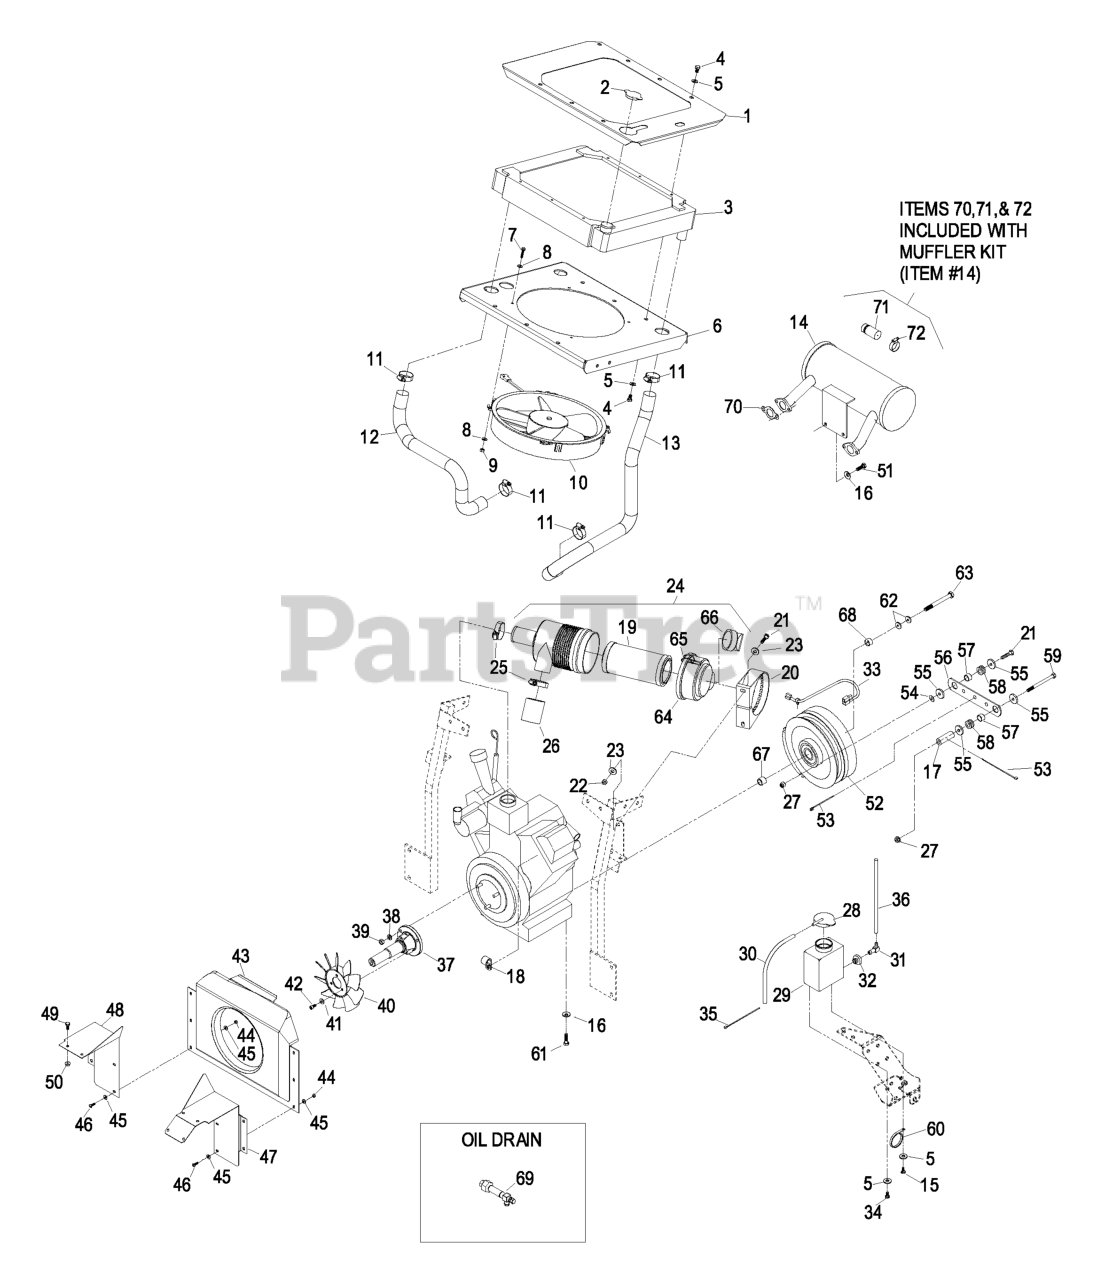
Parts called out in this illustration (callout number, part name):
2	CAP-RADIATOR
3	RADIATOR-MOUNT
4	SCREW-HH
5	WASHER-PLAIN
8	WASHER-FLAT
9	NUT-LOCK, HH
12	HOSE-INLET, RADIATOR
13	HOSE-OUTLET, RADIATOR
14	KIT,MUFFLER W/ARRESTOR
15	SCREW-HH
16	WASHER-BELLEVILLE
17	SPACER-ANCHOR, CLUTCH
18	CLIP-LOOM
20	BRACKET-MOUNTING
21	SCREW-HH
22	NUT-LOCK, NI
23	WASHER-FLAT
24	AIR CLEANER ASM
25	CLAMP-HOSE
26	HOSE-INLET, AIR
28	CAP-TANK, OVERFLOW
29	TANK-OVERFLOW
33	KIT,CLUTCH JUMPER HARNESS
34	SCREW-HH
35	TIE-CABLE
37	EXTENSION-CRANKSHAFT
38	WASHER-LOCK
39	NUT-HEX
40	FAN-PUMP, COOLING
41	WASHER-FLAT
42	SCREW-HSH
43	SHROUD-FAN, HYD
44	NUT-LOCK, NI
45	WASHER-FLAT
46	SCREW-PPH
47	SHIELD-LH
49	SCREW-HH
51	SCREW-HH
53	TIE-PLASTIC
54	WASHER-FLAT
56	STRAP-CLUTCH, BRAKE
58	GROMMET
59	SCREW-HH
60	CLIP-LOOM
61	SCREW-HH
62	WASHER-SPRING
63	SCREW-HH
64	COVER ASM
65	LATCH-CLEANER, AIR
66	VALVE-VACUATOR
67	SPACER-CLUTCH
68	KEEPER-CLUTCH
69	VALVE-DRAIN, OIL
70	GASKET-EXHAUST
71	ARRESTOR-SPARK
72	CLAMP-MUFFLER
